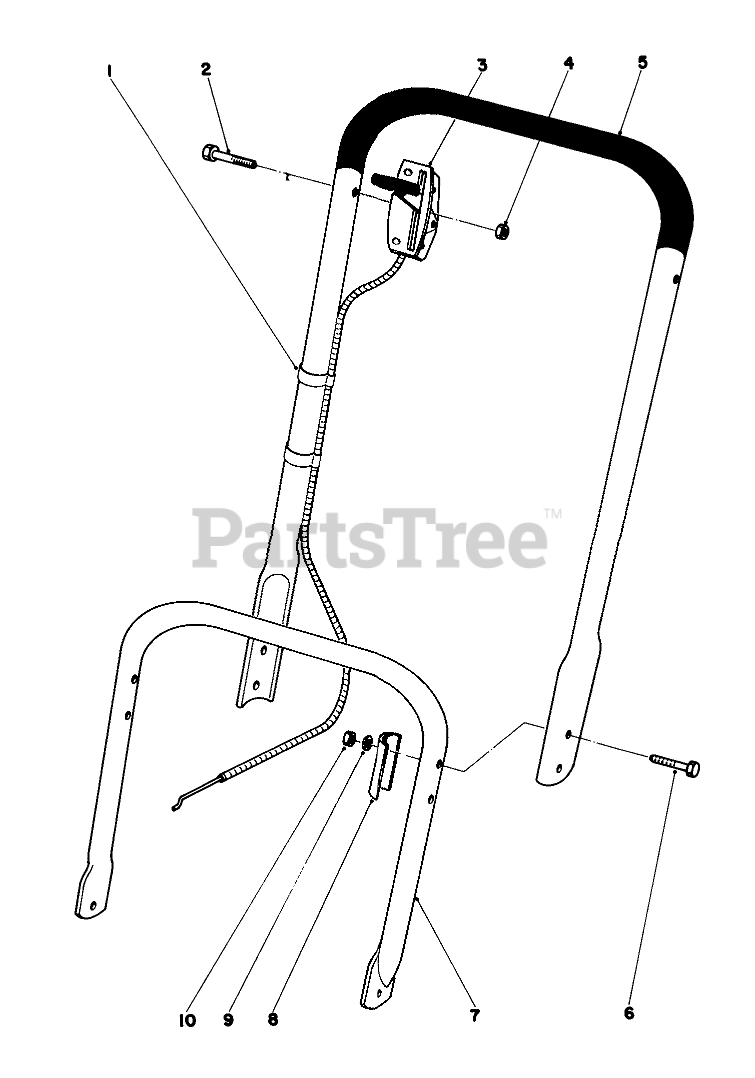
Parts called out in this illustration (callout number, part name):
2	SCREW-HH
3	THROTTLE CONTROL
4	NUT-LOCK, CONE
5	UPPER HANDLE
6	SCREW-HH
7	Handle-Lower
8	Brace-Handle
9	WASHER-LOCK/SP
10	NUT-HEX
